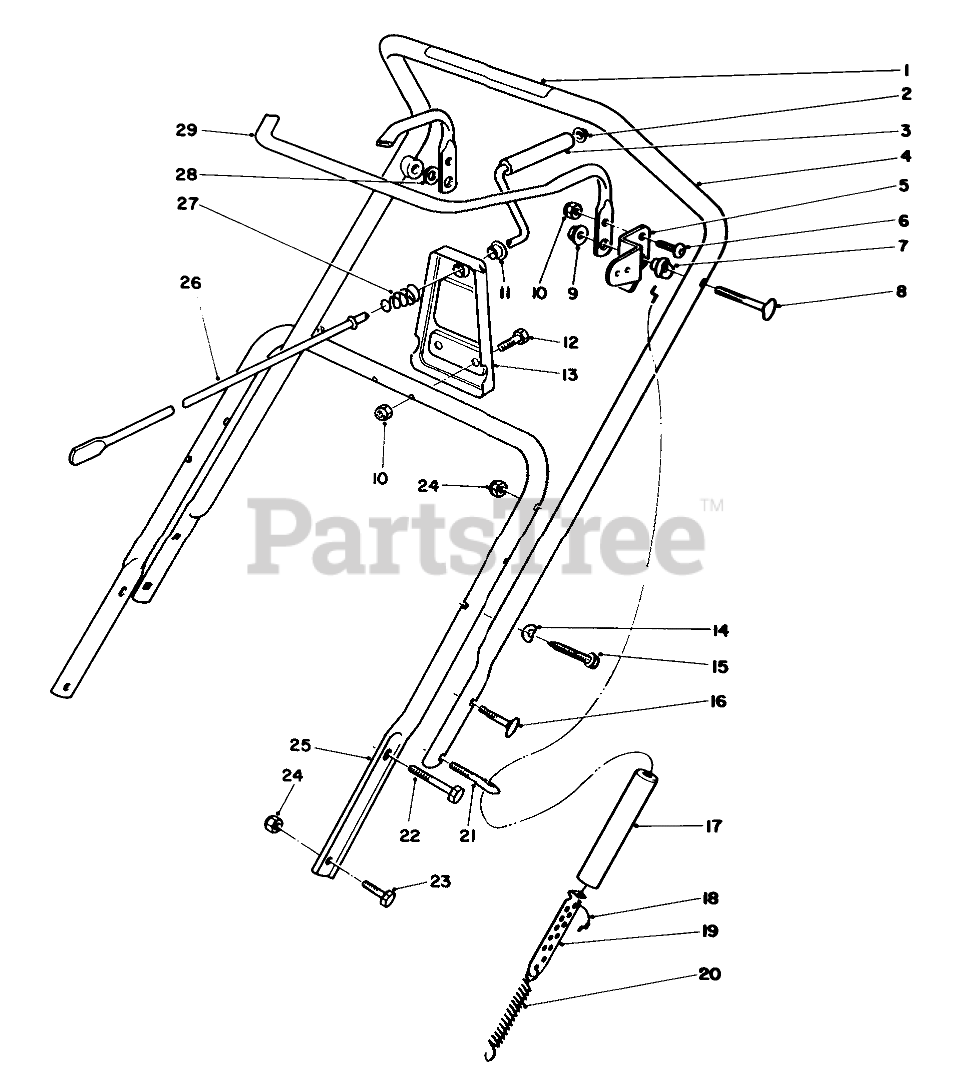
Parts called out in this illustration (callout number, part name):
1	DECAL - ROTOR DRIVE
2	RETAINER-PUSH ON
3	Grip-Rod
4	Upper Handle Assembly (Incl. Ref. #1) (Model No. 38180)
5	Arm-Clutch Cable
6	SCREW-HSBH
7	SPACER-BAR, CONTROL
8	SCREW-HANDLE
9	NUT-LOCK, NI
10	NUT-LOCK, NI
11	Bushing
12	SCREW-HH
13	Support-Crank
14	WASHER
15	SCREW
16	SCREW
17	COVER-SPRING
18	CABLE-CLUTCH
19	ADJUSTER-CABLE
20	SPRING-EXTENSION
21	BOLT-EYE
22	SCREW-HH
23	SCREW-HH
24	NUT-LOCK, NI
25	LOWER HANDLE
26	ROD-CRANK, CHUTE
27	SPRING-COMPRESSION
28	WASHER
29	Bar-Control
